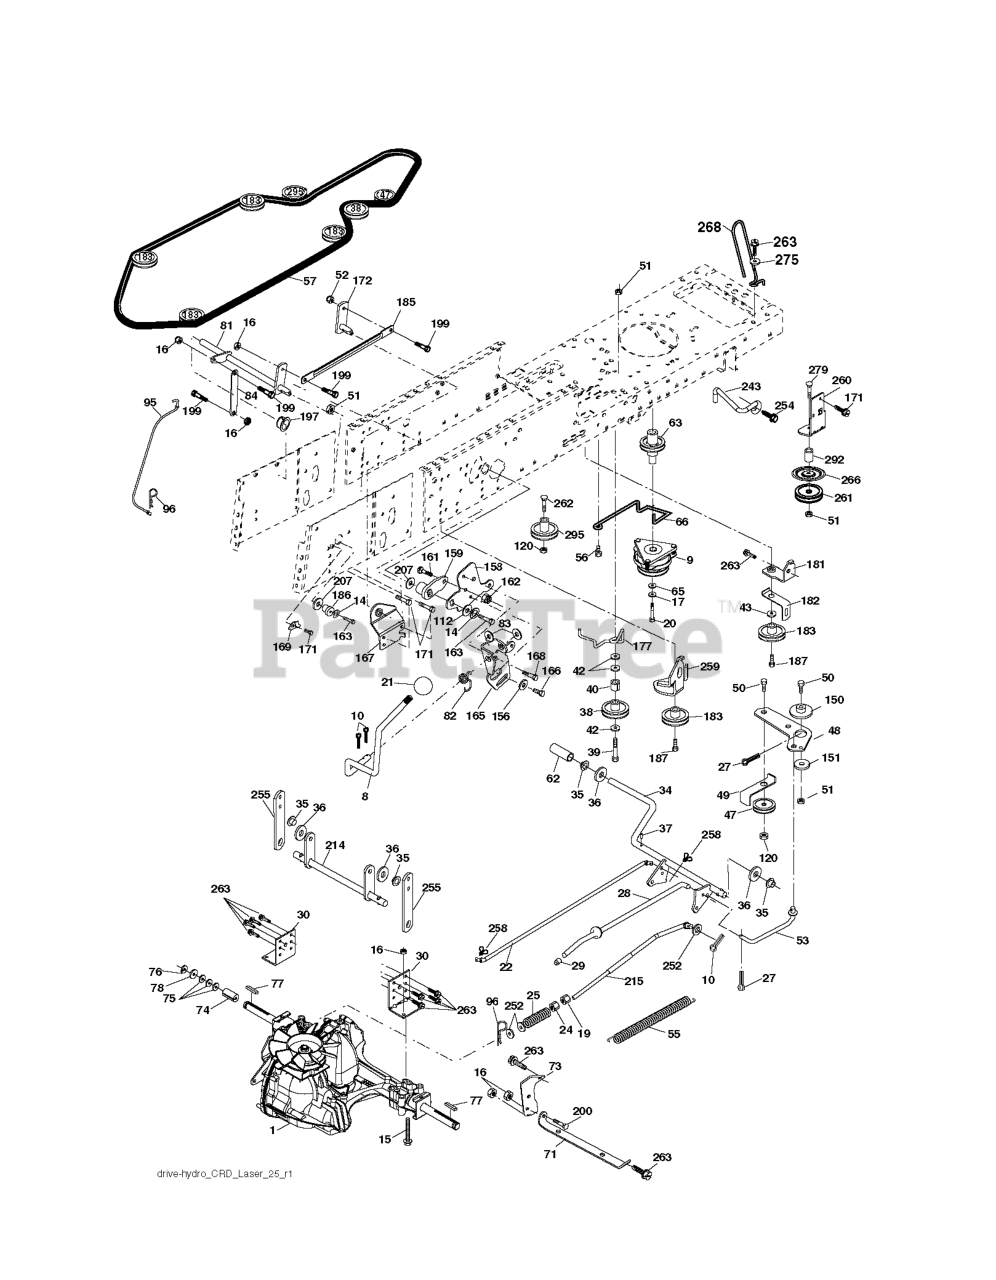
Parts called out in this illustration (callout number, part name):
8	ROD SHIFT FENDER ADJUST LT
9	CLUTCH.ELECTRIC.OGURA.EURO.
10	PIN COTTER
14	LOCKWASHER
15	BOLT HEX 5/16-18 GR 5
16	NUT.71038.31-18.HEX.NYLOCK
19	NUT
20	BOLT HEX 7/16-20X4-1/4"
21	KNOB.DUCKHEAD.1/2
22	ROD
24	NUT
25	SPRING BRAKE ROD
27	COTTER PIN
28	ROD, PARKING BRAKE
29	CAP
30	BRKT, TRNSXLE MNT 20"
34	SHAFT, FOOT PEDAL
35	BEARING.NYLON
37	DRIVE PIN
38	PULLEY.FLAT
42	WASHER
47	IDLER PULLEY
48	BELLCRANK, CLUTCH
49	RETAIN BELT
50	BOLT.3/8-16X1.50
52	LOCKNUT
53	LINK.CLUTCH.7.66.2005
55	SPRING, RETURN LT
56	SCREW.3/8-16
57	V-BELT 113"
62	PEDAL COVER T
63	PULLEY.ENGINE.CVX.LT
65	LOCKWASHER
66	KEEPER BELT ENGINE
71	STRAP TORQUE LH HYDRO
73	STRAP TORQUE RH HYDRO
74	SPACER AXLE
77	SQUARE KEY
81	ASM.CROSS.SHAFT.REAR.CRD.0510
82	SHIFT SPRING
83	WASHER
84	LINK.PNT.TRANSAXLE.0510.CRD
95	LINK
96	RETAINER M
120	NUT LOCK FLG 3/8-16 UNC
150	BUSHING.BELLCRANK.GRD.DR
151	WASHER 12/32X2X10GA
156	WASHER.SRRTD.5/16
158	BRACKET
159	RB HUB.SHIFT
161	BOLT
162	NUT.CROWNLOCK.1/4
165	RP BRACKET
166	CAPSCREW.HXHD.FLG.5/16-18X.625
167	BRACKET.SUPT.SHIFT.CRD
168	BOLT.SHOULDER.5/16-18X
169	PLATE.FASTENING.CROSS.SHAFT
172	LINK
181	BRACKET
182	BELT GUIDE
183	PULLEY.V-IDLER.GRND.DR
185	LINK
186	HUB.TAPERED.ROUND.CRD
187	BOLT.5/16-18X1.25
197	NYLINER SNAP 5/8" ID
199	BOLT SHOULDER 5/16-18 UNC
207	WASHER NYL
214	LEVER
215	ROD
243	BRACKET, ANTI-ROTATION
252	WASHER
254	SCREW 3/8-16X1
255	SHAFT
258	CLIP RETAINER
259	BRACKET
261	FLAT IDLER PULLEY
263	SCREW, 3/8-16X3/4
266	PROTECTOR
268	GUARD MUFFLER
275	WASHER
292	SPACER
295	PULLEY IDLER COMPOSITE
